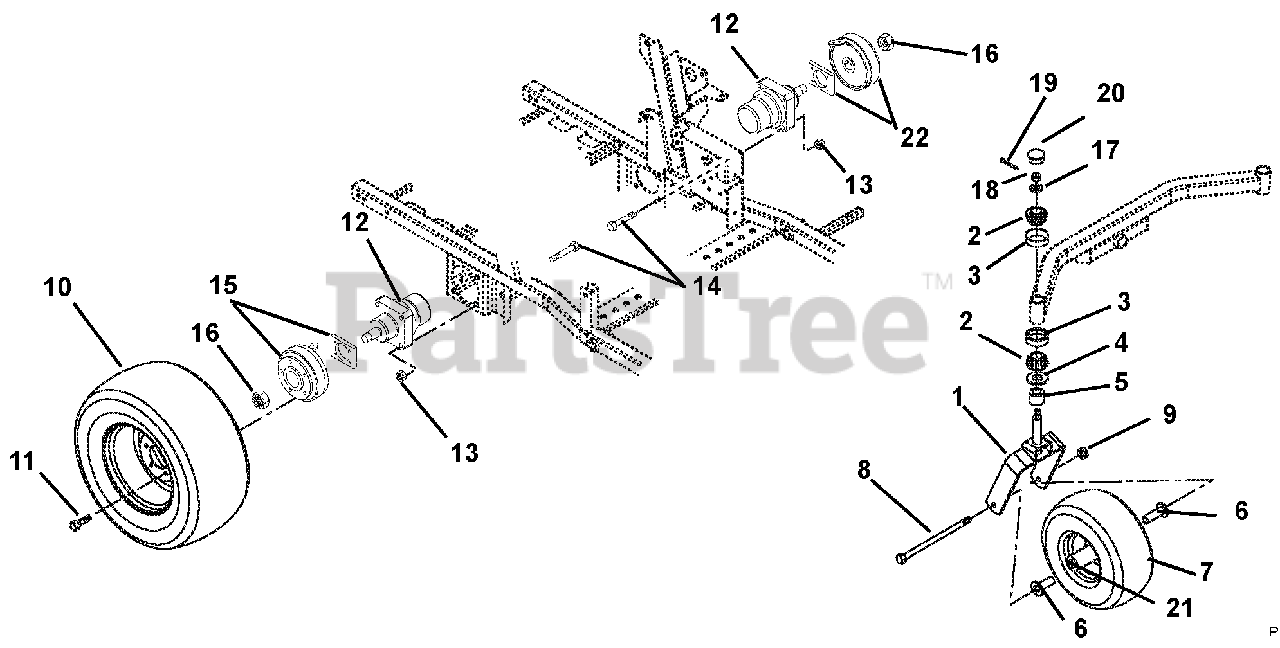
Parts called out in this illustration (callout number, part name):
1	FORK-FRONT
2	BRG, CONE W/ GREASE
3	BRG-CUP1.980X.420
4	BEARING SEAL 1.5 X 2 X .18
5	SPACER 1.005X1.5075X.375
6	SPACER - WHEEL
7	WHEEL/TIRE ASM
8	@BLT-HEX .50-13X9.00 GR5 YWZC
9	@NUT-LK-CTR .50-13 YWZC
10	TIRE/WHEEL ASSY 24X12-12
11	BLT, LUG .50-20 X 1.38
12	MOTOR, PARKER WHEEL
13	@NUT-LK-TOP-FLG .50-13 YWZC
14	BOLT, WHEEL MOTOR 1/2-13X2.75
15	BRAKE, RH PARK (WOODS LH)
16	NUT-LK-JAM-PTCH 1.00-20
17	WSHR-FL-STL.755X1.375X.062YWZC
18	NUT, SLOTTED .75-16
19	@PIN-CTR .16X1.00 EXTPRSQCT YZ
20	CAP,DUST
21	BRG, 25MM ID X 52MM OD X 15MM
22	BRAKE, LH PARK (WOODS RH)
